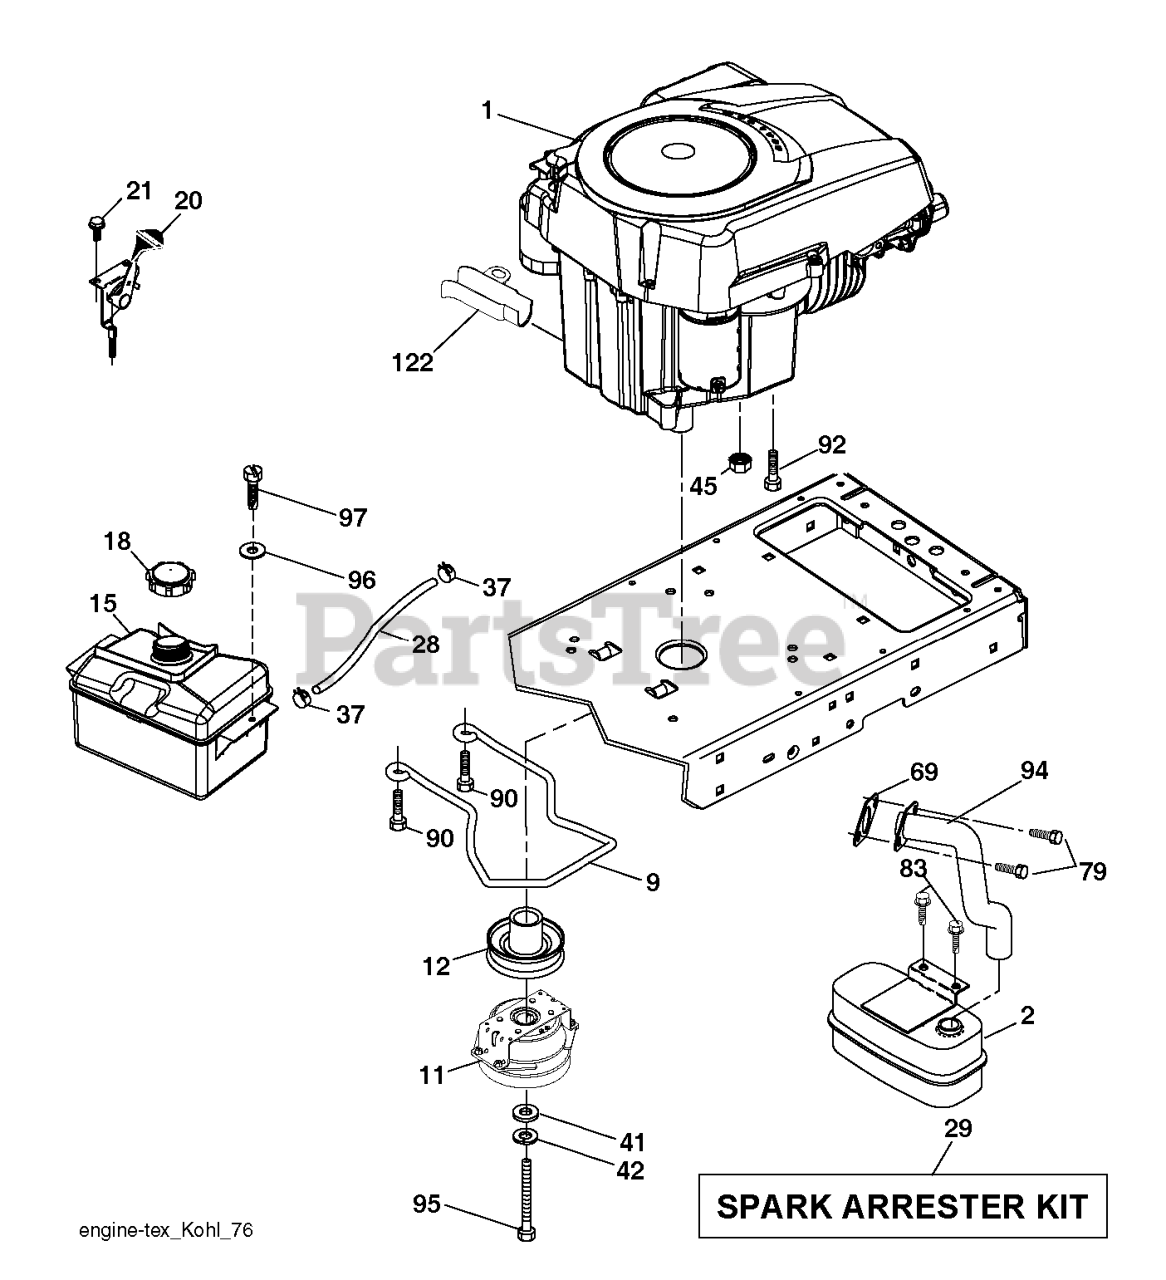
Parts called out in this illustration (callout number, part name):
2	MUFFLER.ASM.SINGLE
9	KEEPER.BELT.ENG.4.25"2.BLT.431
11	CLUTCH.OGURA.4.4PD.GT1.5-EH13V
12	PULLEY.ENGINE.TUFFTORQ
15	FUEL.TANK.ASM.NON-EPA
18	CAP ASM.FUEL.2.25"FR.
20	CONTROL.TH/CK.C.
21	SCREW.#10 X 0.750.BOS
28	LINE.FUEL.20
29	KIT.SPARK ARRESTOR 794945 B&S
37	HOSE CLAMP
42	WASHER 7/16 LOCK
45	NUT
69	GASKET.EXHAUST.KOHLER
79	SCREW.SOCKET HD.5/16-1
83	BOLT.5/16-18UNCX3/4 W/SEMS.BLK
90	SCREW 3/8-16X1
92	SCREW 3/8-16X1
94	TUBE.EXHAUST.KOHLER.COURAGE
95	CLUTCH BOLT7/16-20X3.5 GR524HR
97	SCREW HEXWSHR 1/4-20X3/4
122	EXTENSION DRAIN OIL
